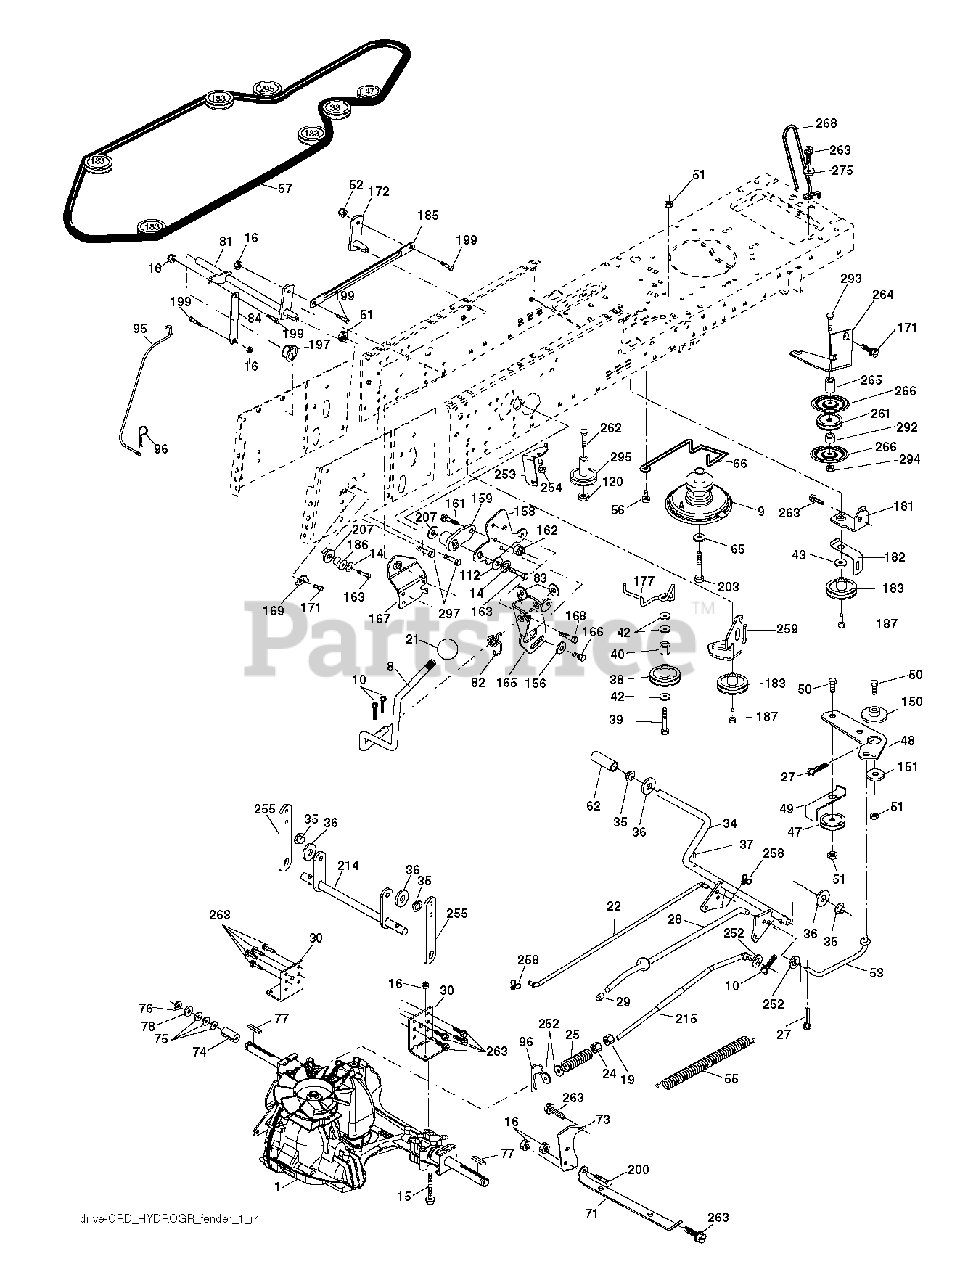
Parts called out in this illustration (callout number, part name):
8	ROD SHIFT FENDER ADJUST LT
14	LOCKWASHER
15	BOLT HEX 5/16-18 GR 5
16	NUT.71038.31-18.HEX.NYLOCK
19	NUT
21	KNOB T (1/2-HOLE)
24	NUT
27	COTTER PIN
28	ROD, PARKING BRAKE
30	BRKT, TRNSXLE MNT 20"
34	SHAFT, FOOT PEDAL
35	BEARING.NYLON
37	DRIVE PIN
42	WASHER
47	IDLER PULLEY
48	BELLCRANK, CLUTCH
50	BOLT.3/8-16X1.50
51	LOCKNUT
52	LOCKNUT
53	LINK.CLUTCH.7.66.2005
55	SPRING, RETURN LT
57	V-BELT 113"
62	PEDAL COVER T
65	LOCKWASHER
66	KEEPER BELT ENGINE
71	STRAP TORQUE LH HYDRO
73	STRAP TORQUE RH HYDRO
81	SHAFT ASSY
83	WASHER
84	LINK.PNT.TRANSAXLE.0510.CRD
96	RETAINER M
112	WASHER LT
120	NUT LOCK FLG 3/8-16 UNC
150	BUSHING.BELLCRANK.GRD.DR
151	WASHER 12/32X2X10GA
156	WASHER.SRRTD.5/16
158	BRACKET.SHIFT.MOUNT
161	BOLT
162	NUT.CROWNLOCK.1/4
165	BRACKET.PIVOT.LEVER
167	BRACKET
168	BOLT.SHOULDER.5/16-18X
169	PLATE.FASTENING.CROSS.SHAFT
183	PULLEY.V-IDLER.
187	BOLT.5/16-18X1.25
197	NYLINER SNAP 5/8" ID
199	BOLT SHOULDER 5/16-18 UNC
200	BOLT
203	BOLT.HEX.7/16-20x5
252	WASHER
254	SCREW 3/8-16X1
258	CLIP RETAINER
261	FLAT IDLER PULLEY
263	SCREW, 3/8-16X3/4
275	WASHER
294	NUT, HEX 3/8-16
295	PULLEY IDLER COMPOSITE
297	SCREW LT.3/8-46X5/8
